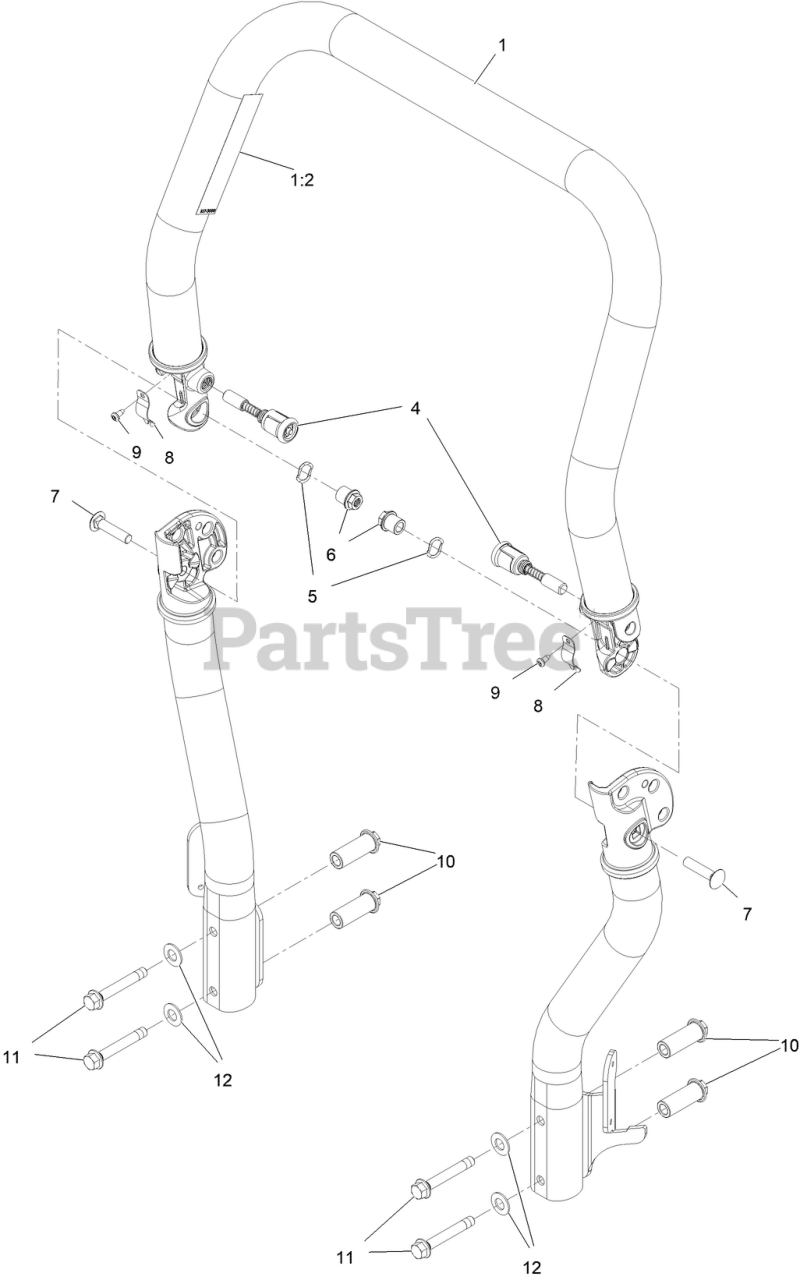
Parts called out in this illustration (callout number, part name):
1	ASM, ROPS Upper W/ Decal
1:2	DECAL-WARNING
4	PIN-SPRING
5	WASHER, WAVE
6	Nut, ROPS Pivot
7	Bolt,CARR, Spcl
8	SPRING, ROPS
10	SPACER, ROPS
11	Bolt, Shoulder
12	WASHER, BELLEVILLE
